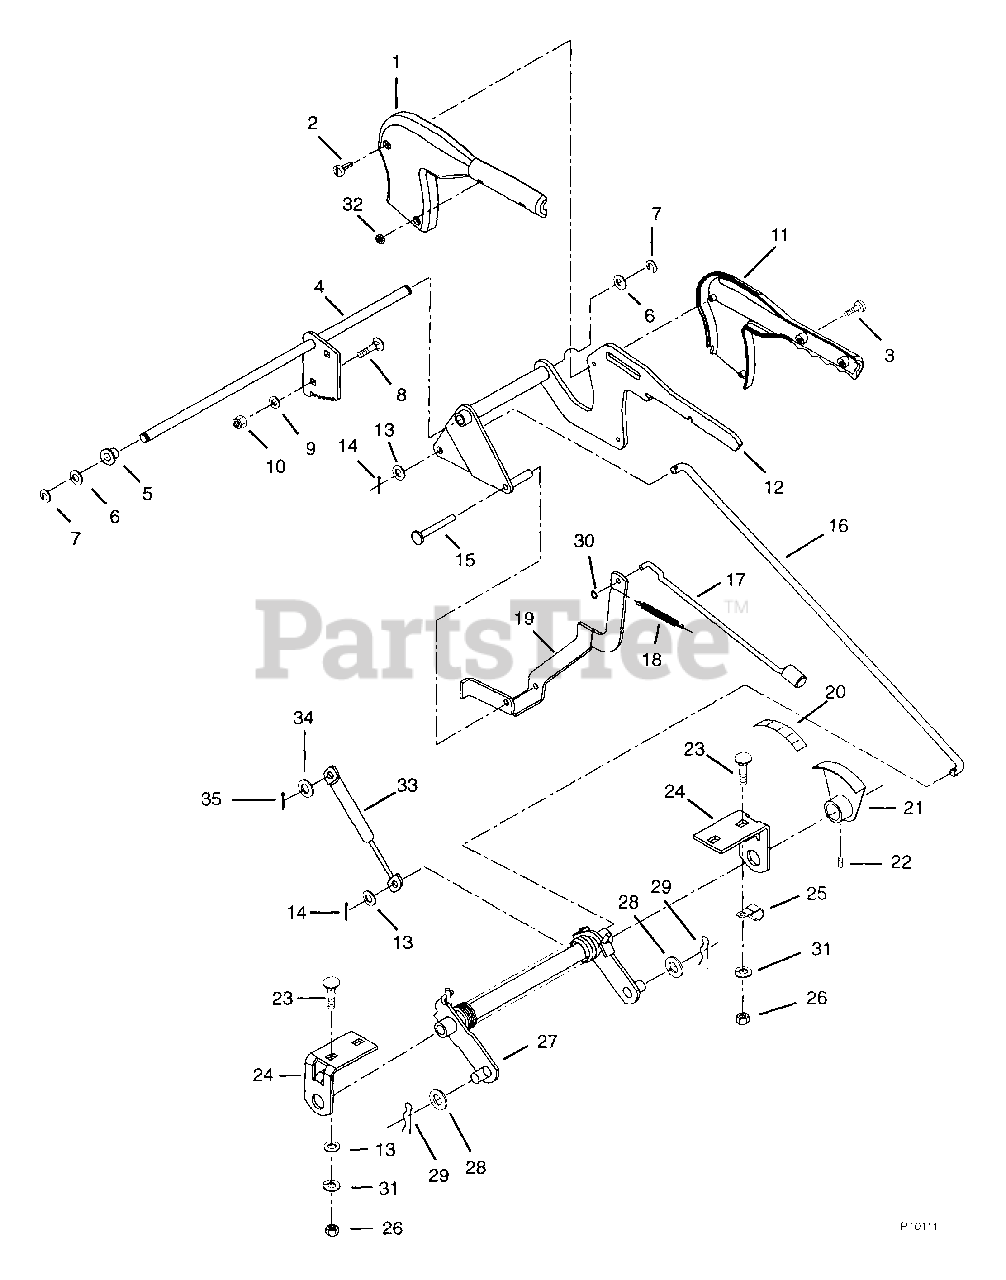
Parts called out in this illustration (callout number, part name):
1	COVER - LIFT RH
2	SCR-TAP 10-16X1.125HI-LOTPHBL
3	SCR-MCH 10-24X.62 SLRH PL
4	PIVOT- LIFT LEVER
5	BSHG-FLG .508X.873X.375X1.19
6	WSHR-FL-STL .520X.827X.062 YZ
7	RG-RTNG-EXT .500X.460
8	BLT-RDHDSQNK .31-18X.75
9	WSHR-FL-STL .323X.625X.062 PL
10	NUT-LK-NYL.312-18 PL
11	COVER - LIFT LH
12	LEVER - LIFT
13	WSHR-FL-STL.406X.812X.065PL
14	PIN-COTR .12X1.0 PL
15	PIN, PIVOT .312 X 2.56
16	LINK, LIFT
16	LIFT LINK
17	PIN - LIFT
18	SG-TENS .048X.44X2.25 WLD 9
19	LEVER - DETENT
20	DECAL - INDICATOR 5 POS
21	INDICATOR - DECK HEIGHT
22	SCR-SET .25-20X.25 SKHCUP OH
23	BLT-RDHDSQNK .38-16X.75 SHT PL
24	BRACKET - CENTER LIFT
25	J-CLAMP
26	NUT-HEX .375-16
27	LEVER - CENTER LIFT
28	WSHR-FL-STL .630X1.005X.062 PL
29	PIN-HAIR EXT .12X.31X2.37 PL
30	RG-RTNG-EXT .250X.010
31	WSHR-LK .375X.094 MED PL
32	NUT-LK 10-24 NY PL
33	SG-GAS COMP .315X.75X10.00 120
34	WSHR-FL-STL .38X.875X.083 PL
35	PIN-COTR .12X.75 PL
